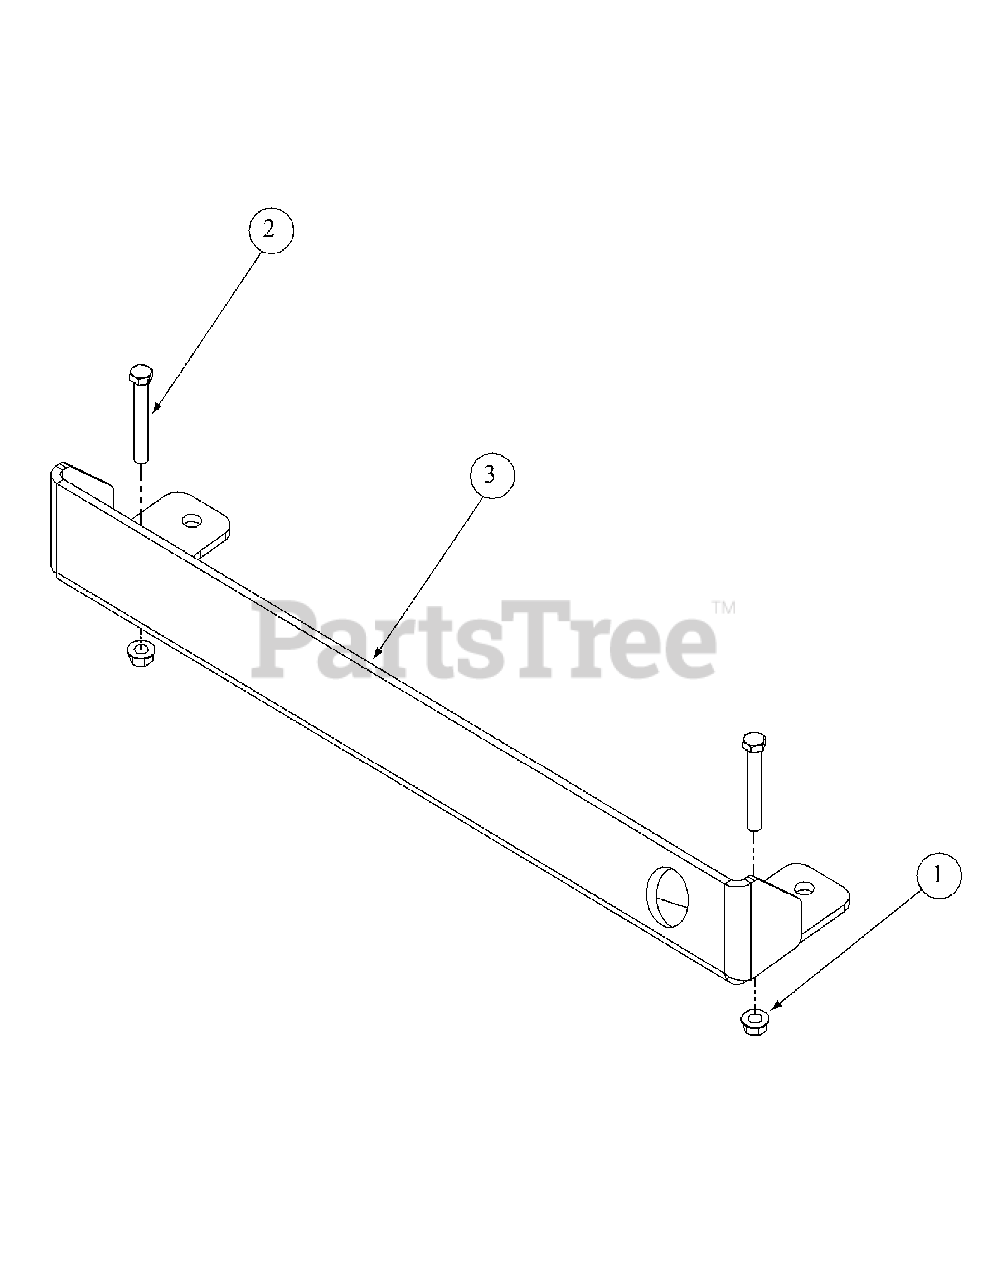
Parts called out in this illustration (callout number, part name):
1	Hex Nut, 1/2-13, Insert Lock
2	HHCS, 1/2-13, 3.00
3	Rear Bumper Plate
